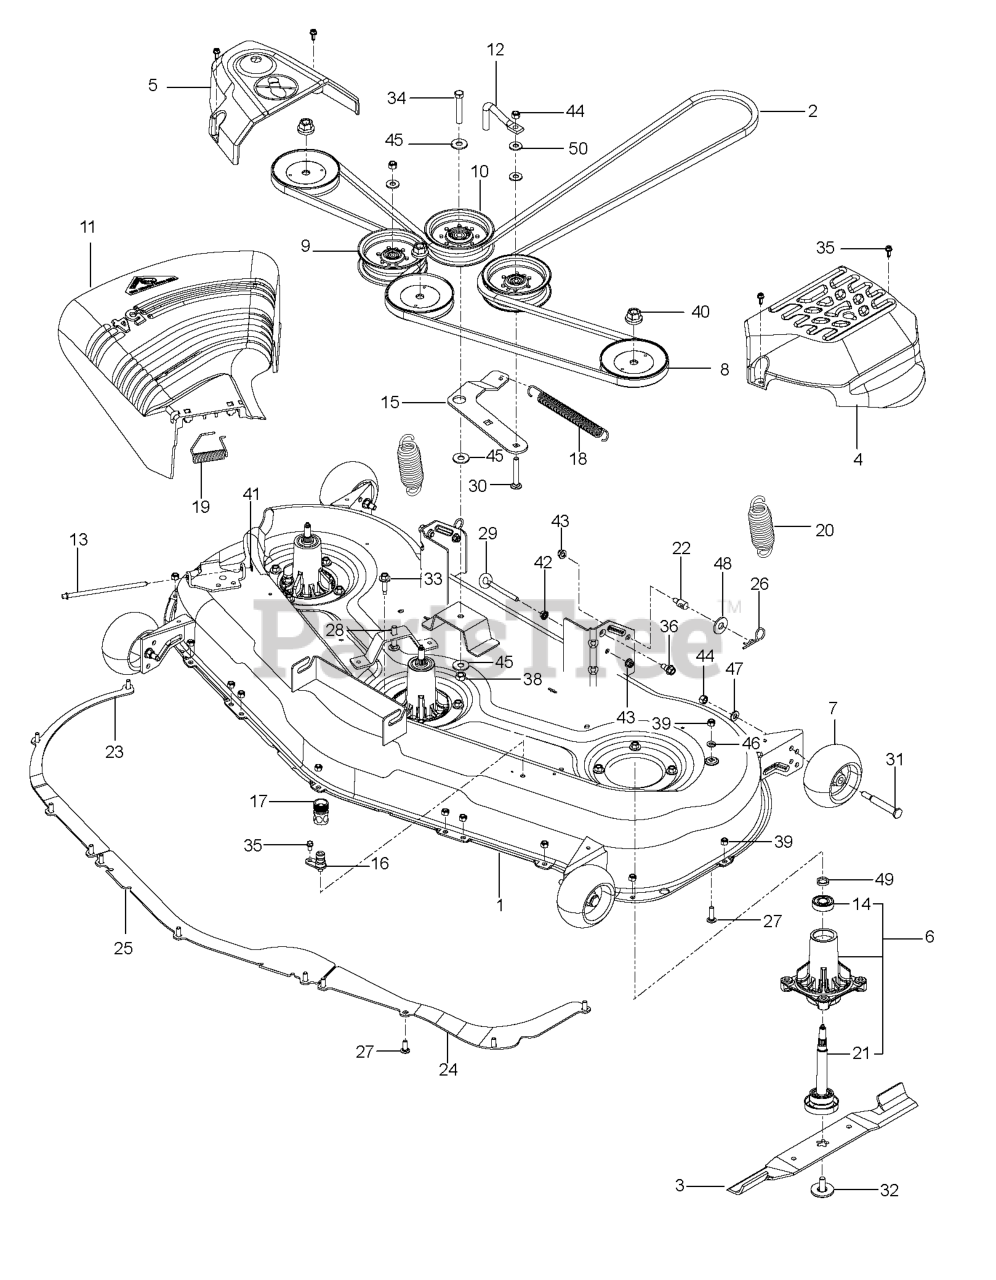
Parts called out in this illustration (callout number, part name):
1	DECK W/DECALS - RZ54
2	BELT.DECK.52".54"
3	BLADE.BAGGING.54"
4	COVER.MANDREL.LH.DECK.54"
5	COVER.MANDREL.RH.DECK.54"
6	MANDREL.W/SPCR.BRG.TALL.NONREV
7	GAUGE WHEEL
8	PULLEY
9	PULLEY.IDLER.2006
10	PULLEY.IDLER.MWR.STATI.LH
11	DEFLECTOR, 54"
12	BELT KEEPER 5"
13	ROD, HINGE
14	BEARING.MANDREL.TOP.EXTENDED
15	ARM.IDLER.BLACK
16	PORT.WASHOUT
17	COUPLING.QUICK CONNECT
18	SPRING, DECK BELT
19	TORSION SPRING
21	SHAFT ASSY, MANDREL SHAFT
22	STUD.FASTNER.W/ANTI-ROTATE
23	BAFFLE, RIGHT 54"
24	BAFFLE LEFT 54
25	BAFFLE, CENTER, 54"
26	HAIRPIN #4
27	Bolt Rdhd Sqnk 5/16-18 Unc x 3/4
28	BOLT.RDHD.SQNK.3/8-16UNC X 2
29	EYE BOLT 5/16 X 3.50
30	CARRIAGE BOLT 3/8-16 X
31	SHOULDER BOLT 1/2X2-5/8 ZD SPE
32	BLADE BOLT ASSY-7/16" TB REPL
33	WASHER HEAD SCREW
34	BOLT.HEX.7/16-14
35	SCREW.1/4-20X5/8
36	BOLT.SHOULDER
38	7/16-14 HEX NUT W/NYL RING ZD
39	NUT 5/16 NYLOC
40	NUT.FLANGE.LOCK.TOP
41	NUT PUSH M
42	NUT 5/16C WHIZ
43	5/16-18 NYLOC FLANGE NUT
44	NUT 3/8-16 NYLOC
45	WASHER 7/16 FLAT ZD
46	WASHER
47	WASHER 3/8 SAE FLAT
48	WASH USS FLAT 1/2
49	WASHER.SPACER.MANDREL
50	RP WASHER 3/8 FLAT
